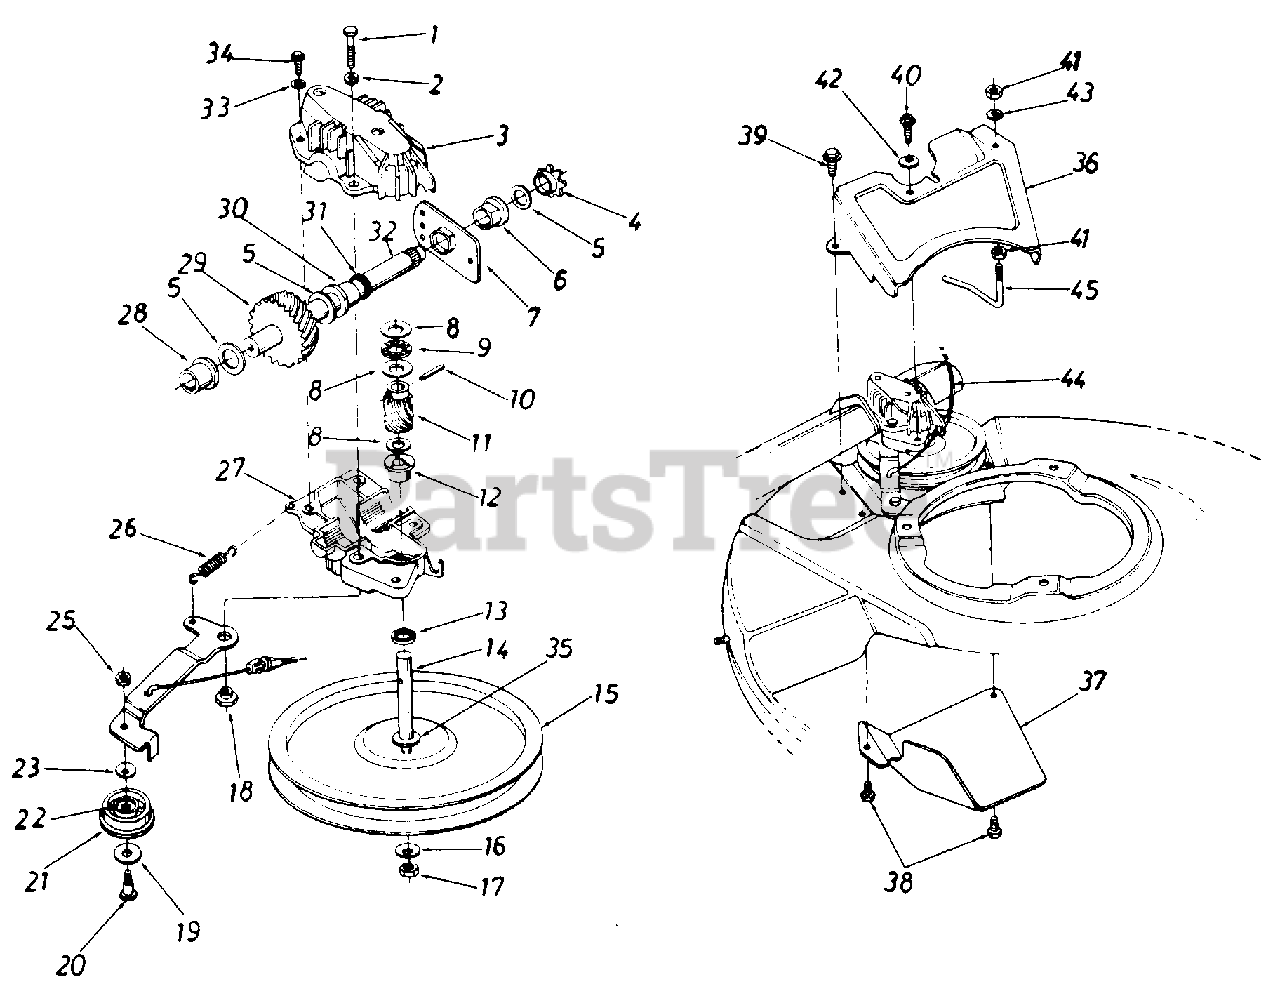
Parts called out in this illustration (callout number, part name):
1	Hex Bolt 1/4-20 x 1.25" Lg.
2	L-Wash. 1/4" I.D.
3	Upper Hsg. Half
4	#48 Sprocket 7 Tooth x 1/2 Pitch
5	Fl-Wash. 518" I.D. x .030
6	Hex Flange Brg. .631" I.D.
7	Hex Bearing Cup
8	Thrust Wash. .382" I.D. x .70" O.D.
9	Thrust Bearing .375" I.D. x .812" O.D.
10	Spring Pin Spir. 1/8" x .62" Heavy
11	11 Tooth Helical Gear
12	Flange Bearing
13	Oil Seal
14	Pulley-Transmission Shaft
15	Fl-Pulley 5.06" kD.
16	Bell-Wash. .265" I.D. x .75"
17	Hex Nut 1/4-28 L.H. Thd.
18	Shld. Spacer .375" Dia. x .1 70
19	Fl-Wash. .390" I.D. x l.O"
20	Shld. Bolt .375" Dia. x .40"
21	Fl-Idler Plastic 1.50" Dia.
22	Needle Brg. .375" x .31"
23	Bell-Wash. .265" I.D. x 75"
25	Hex Patch L-Nut 1/4-28 Thd.
26	Extension Spring 1.12" Lg.
27	Lower Hsg. Half
28	Flange Bearing .566 Dia.
29	33 Tooth Helical Gear
30	Flange Bearing .629 Dia.
31	Oil Seal .625 Dia.
32	Gear Sprocket Shaft,
33	L-Wash. #10 I.D.
34	Hex B-Tap Scr. #10 x .62"
35	Hex Washer .26" x .88"
36	Transmission Belt Guard
39	Hex AB-Tap Scr. 1/4 x .50" Lg.
40	Hex B-Tap Scr. 1/4 x .62" Lg.
41	Hex Nut 1/4-20 Thd.
42	Bell-Wash. .265" I.D. x 75"
43	L-Wash. 1/4" I.D.
44	S.P. Cable-50" Lg.
45	S.P. Belt Guard
